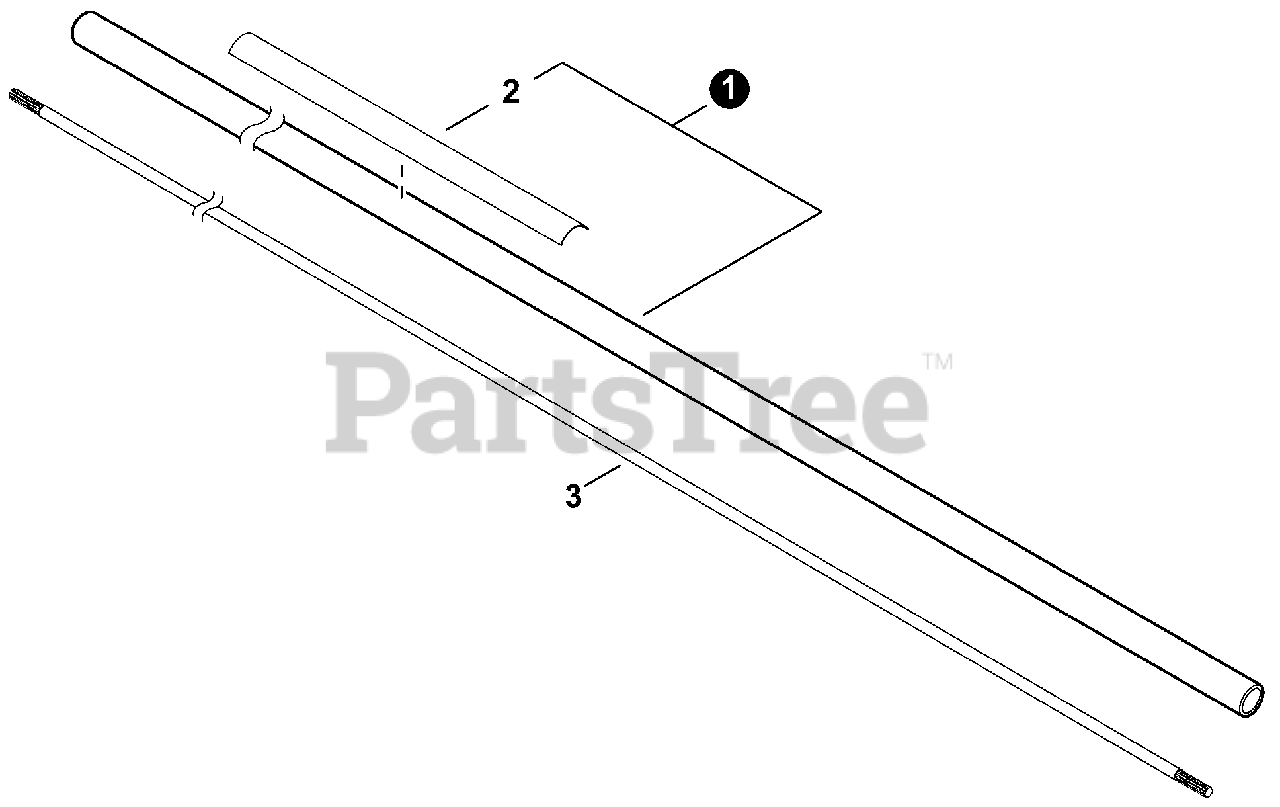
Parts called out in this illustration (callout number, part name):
1	MAIN PIPE ASSY
2	LABEL - CAUTION - ISO
3	DRIVESHAFT
